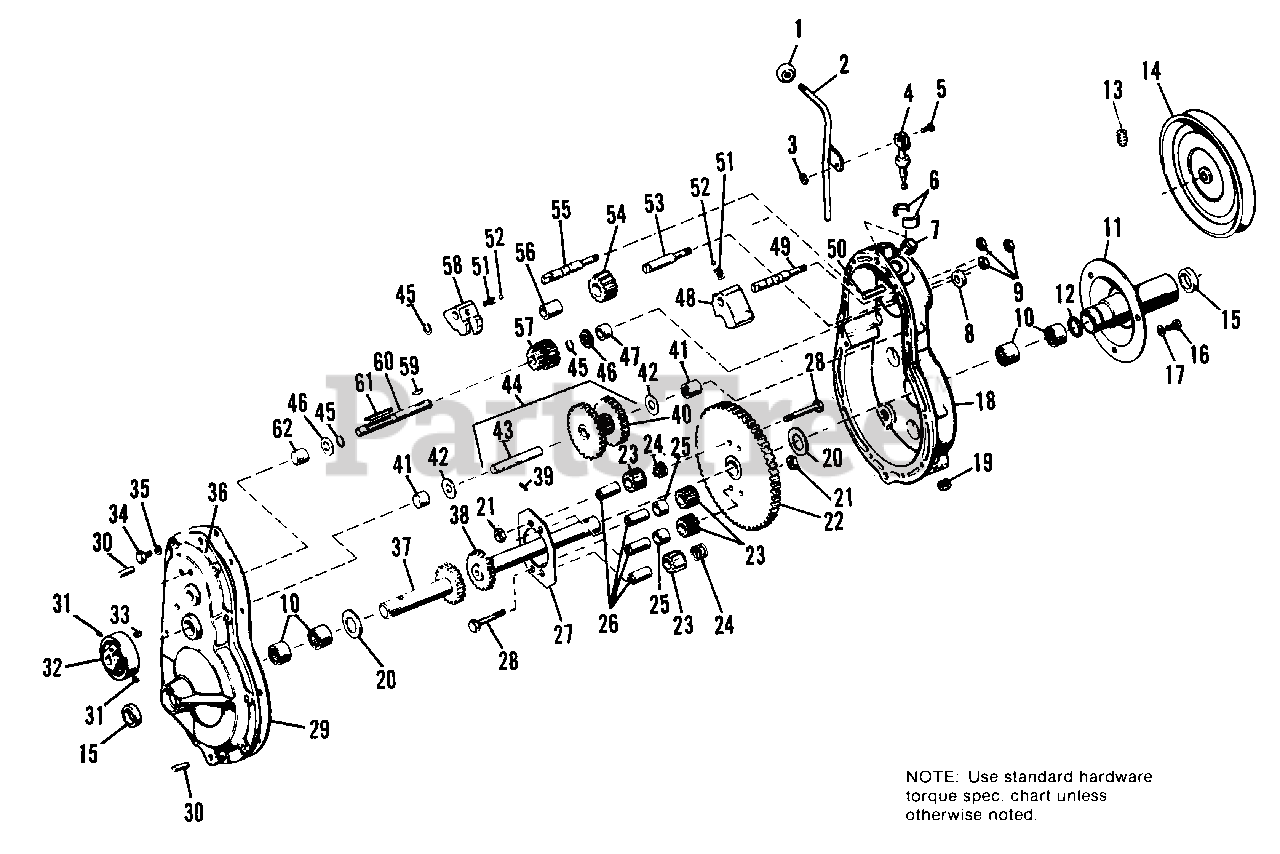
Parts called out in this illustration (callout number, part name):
2	LEVER ASSY., Shift
3	LOCKNUT, Hex, 1/4-20
4	ROD ASSY., Shift
5	CAPSCREW, Hex Hd., 1/4-20 x 3/4
6	BUSHING, Half
9	NUT, Hex, Full, 7/16-14
10	BEARING, Roller
11	HOUSING ASSY., Axle
13	SETSCREW, 3/8-24 x 3/8
16	CAPSCREW, Hex Hd., 3/8-16 x 7/8
17	LOCKWASHER, 3/8
18	CASE ASSY., Gear
19	PLUG, Pipe, 3/8
21	LOCKWASHER, 3/8-16
22	GEAR ASSY., Drive
23	PINION, Diff.
25	SPACER, Diff.
26	SPINDLE, Diff.
27	PLATE, Diff.
28	CAPSCREW, Hex Hd., 3/8-16 x 2-1/2
30	PIN, Roll, 3/8 x 1
31	SETSCREW, 5/16-18 x 5/16
32	DRUM, Brake
34	CAPSCREW, Hex Hd., 5/16-18 x 1-1/4
35	LOCKWASHER, 5/16
36	COVER ASSY., Gear Case
37	SHAFT ASSY., Axle, L.H.
38	SHAFT ASSY., Axle, R.H.
39	PIN, Dowel
40	GEAR ASSY., Cluster
41	BEARING, Roller
43	SHAFT, Brake
44	GEAR ASSY., Cluster
45	RING, Retaining
47	BEARING, Roller
48	FORK, Shift I & II
49	SHAFT, Shift, Hi-Lo
50	PIN ASSY., Roll
52	BALL, Shift Lock
53	SHAFT, Pinion, Reverse
54	PINION, Reverse
55	SHAFT, Shift, Reverse
56	BEARING, Roller
57	PINION ASSY., Hi-Lo
58	FORK, Shift, Reverse
60	SHAFT, Pulley
62	BEARING, Roller
